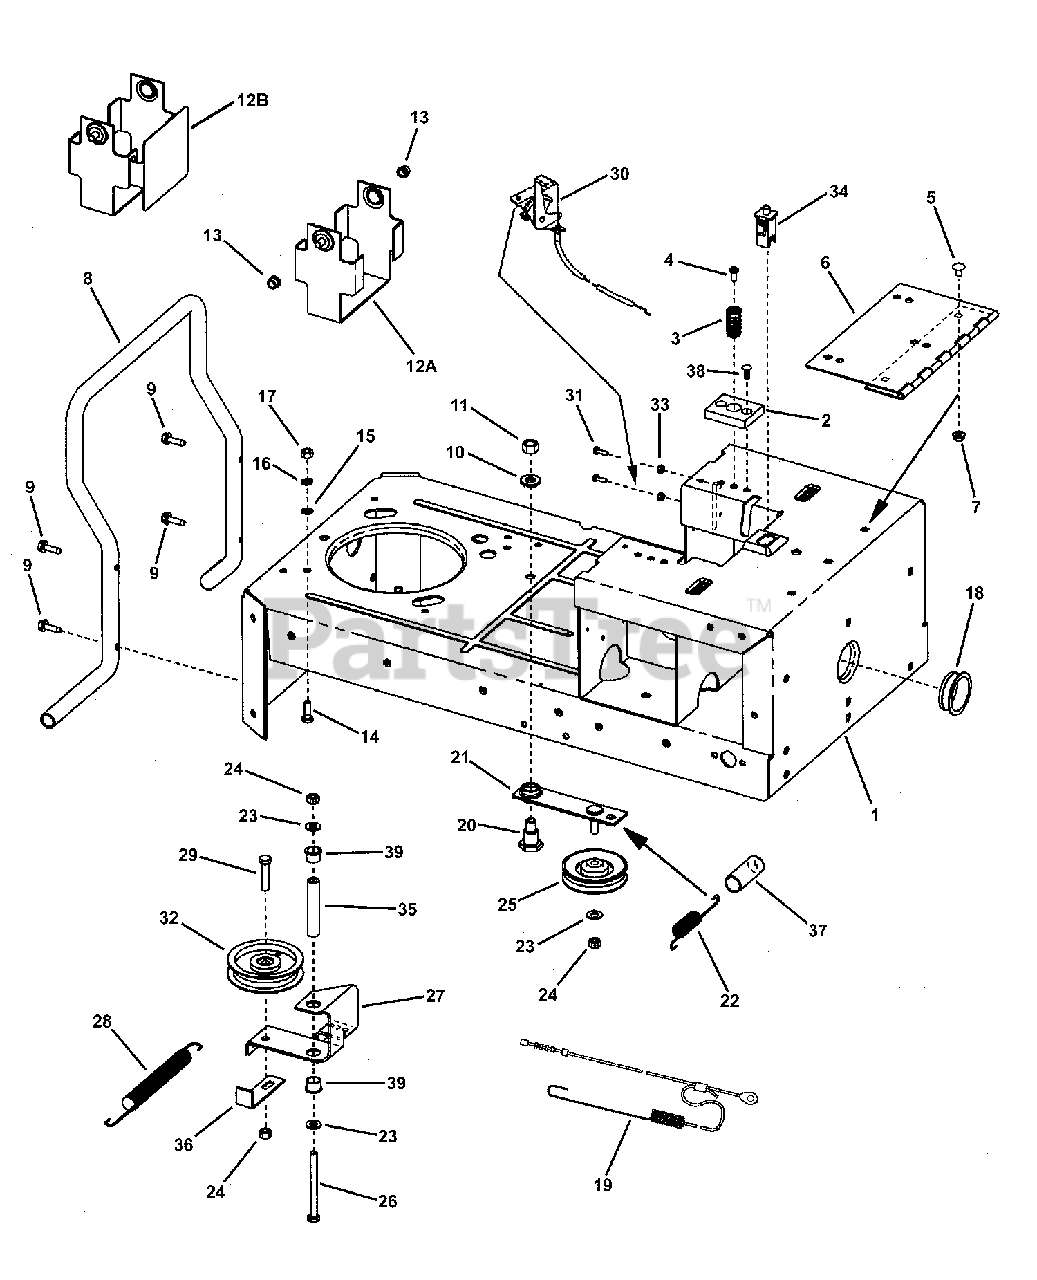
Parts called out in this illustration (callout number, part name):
1	WELDMENT, Rear Frame
2	CUSHION, Seat Support
3	SPRING, Seat Support
4	SCREW, 1/4-20 x 5/8" Pan Head Self-Tap (Torx)
5	BOLT, 5/16-18 x 1/2" Short Neck Carriage, GR5
6	HINGE, Seat
7	NUT, 5/16-18 Hex Flange Lock, GR5
8	BUMPER, Rear
9	SCREW, 5/16-18 x 1-1/2" Hex Washer Self-Tap
10	WASHER, .531 x 1.062 x .121 SAE Flat
11	NUT, 1/2-13 Hex Center Lock, GR5 or B
12A	WELDMENT, Battery Bracket
12B	WELDMENT, Battery Bracket
13	BUSHING, Tie Rod
14	SCREW, 5/16-24 x 1" Hex Head Cap, GR5
15	RETAINER, 5/16" Bolt
16	WASHER, .32 x .58 x .08 Split Lock
17	NUT, 5/16-24 Hex, GR5 or B
18	GROMMET
19	ASSEMBLY, Brake/Clutch Cable
20	BOLT, 1/2-13 Hex Shoulder
21	WELDMENT, Idler Arm, Primary
22	SPRING, Extension- 5" long
23	WASHER, 3/8" SAE Flat
24	NUT, 3/8-16 Hex Center Lock, GR5 or B
25	PULLEY, Idler, V 3.30 HA
26	BOLT, 3/8-16 x 4" Hex Head Cap, GR5
27	BRACKET, Hydro Idler
28	SPRING, Extension, Hydro Idler
29	SCREW, 3/8-16 x 1-3/4" Hex Head Cap, GR5
30	CABLE, Hydro Release Valve
31	SCREW, #10-32 x 5/8" Hex Washer Head Machine
32	IDLER, 4.12" Outside Diameter, Flat
33	NUT, #10-32 Hex Nyloc
34	SWITCH, Seat (NO/NC) Snap-In
35	SLEEVE, Idler
36	GUIDE, Belt
37	COVER-Spring
38	FASTENER, Ratchet
39	BUSHING, Flange, .64 x .75 x .5
